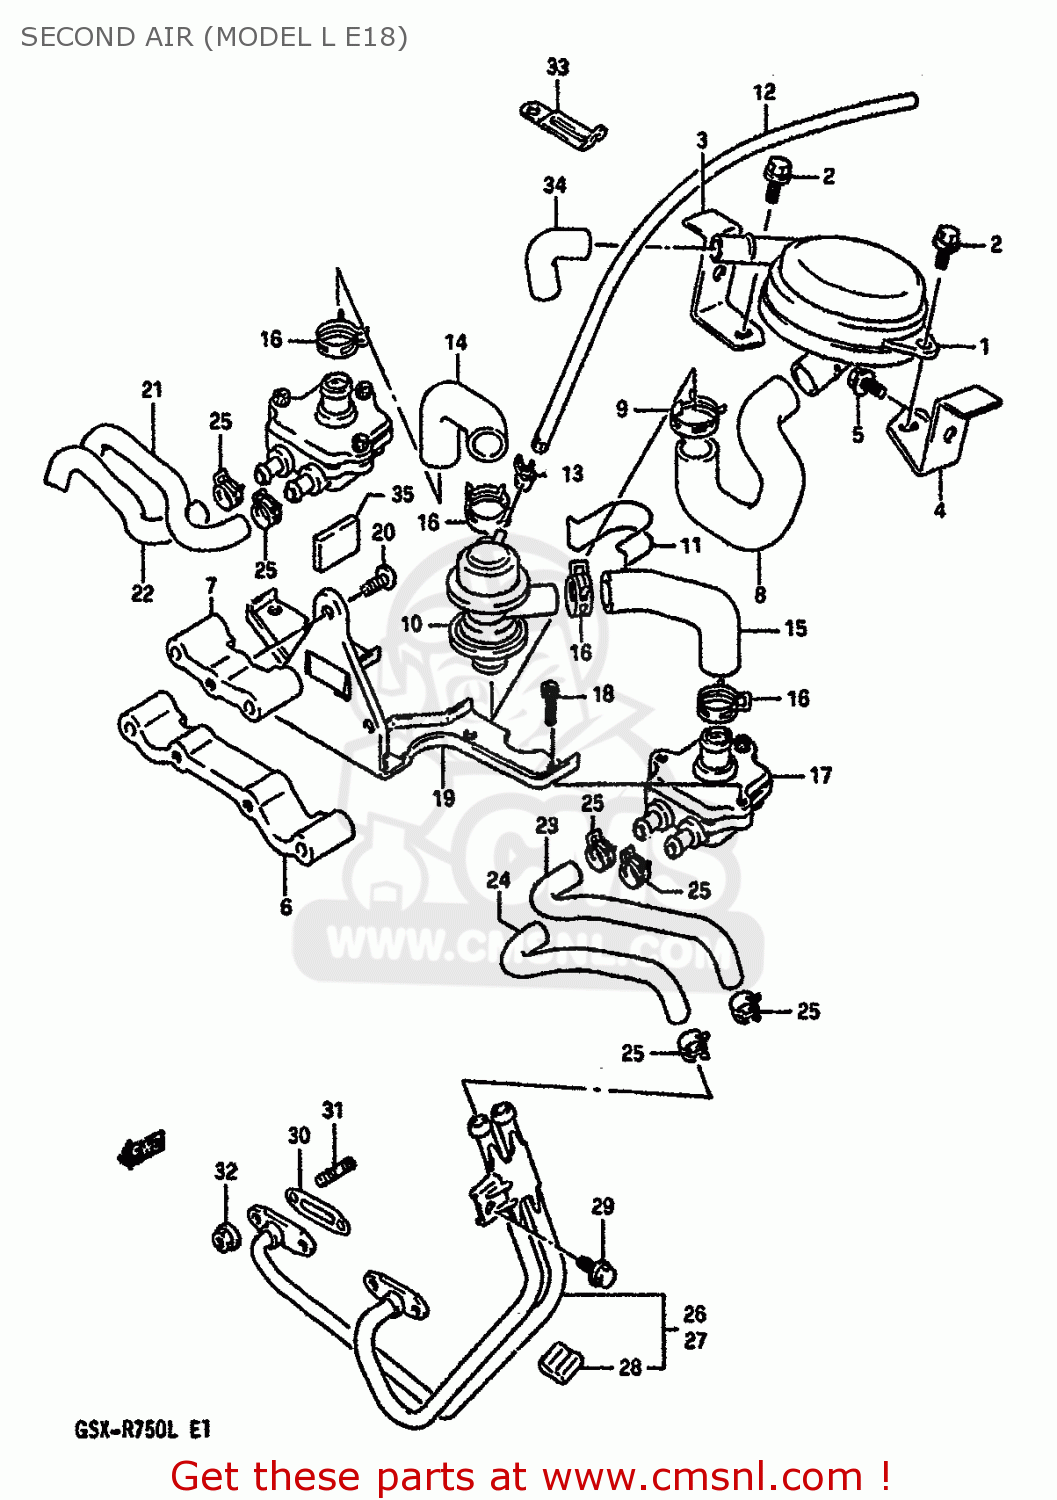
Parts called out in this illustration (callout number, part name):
1	CLEANER ASSEMBLY,SECOND AIR
2	BOLT
3	BRACKET,SECOND AIR CLEANER
4	BRACKET,SECOND AIR CLEANER
5	BOLT
6	SPACER,SECOND AIR BRACKET,LOWER
7	SPACER,SECOND AIR BRACKET,UPPER
8	HOSE,SECOND AIR NO.3
9	CLIP
10	VALVE ASSEMBLY,AIR SWITCH
11	CLAMP,SWITCHING VALVE
12	HOSE,VACUUM
13	CLAMP
14	HOSE,SECOND AIR NO.2,RIGHT
15	HOSE,SECOND AIR NO.2,LEFT
16	CLIP
17	VALVE ASSY,2ND AIR REED
18	BOLT
19	BRACKET,SECOND AIR VALVE
20	SCREW
21	HOSE,SECOND AIR NO.1,RIGHT,INLET
22	HOSE,SECOND AIR NO.1,RIGHT,OUTLET
23	HOSE,SECOND AIR NO.1,LEFT,INLET
24	HOSE,SECOND AIR NO.1,LEFT,OUTLET
25	CLIP
26	PIPE,SECOND AIR,RIGHT
27	PIPE,SECOND AIR,LEFT
28	(CA) CUSHION
29	BOLT 6X12
30	GASKET,SECOND AIR PIPE (NAS)
31	STUD BOLT
32	NUT 6MM
33	CLAMP L:35
34	(CA) HOSE,SECOND AIR CLEANER
35	CUSHION
